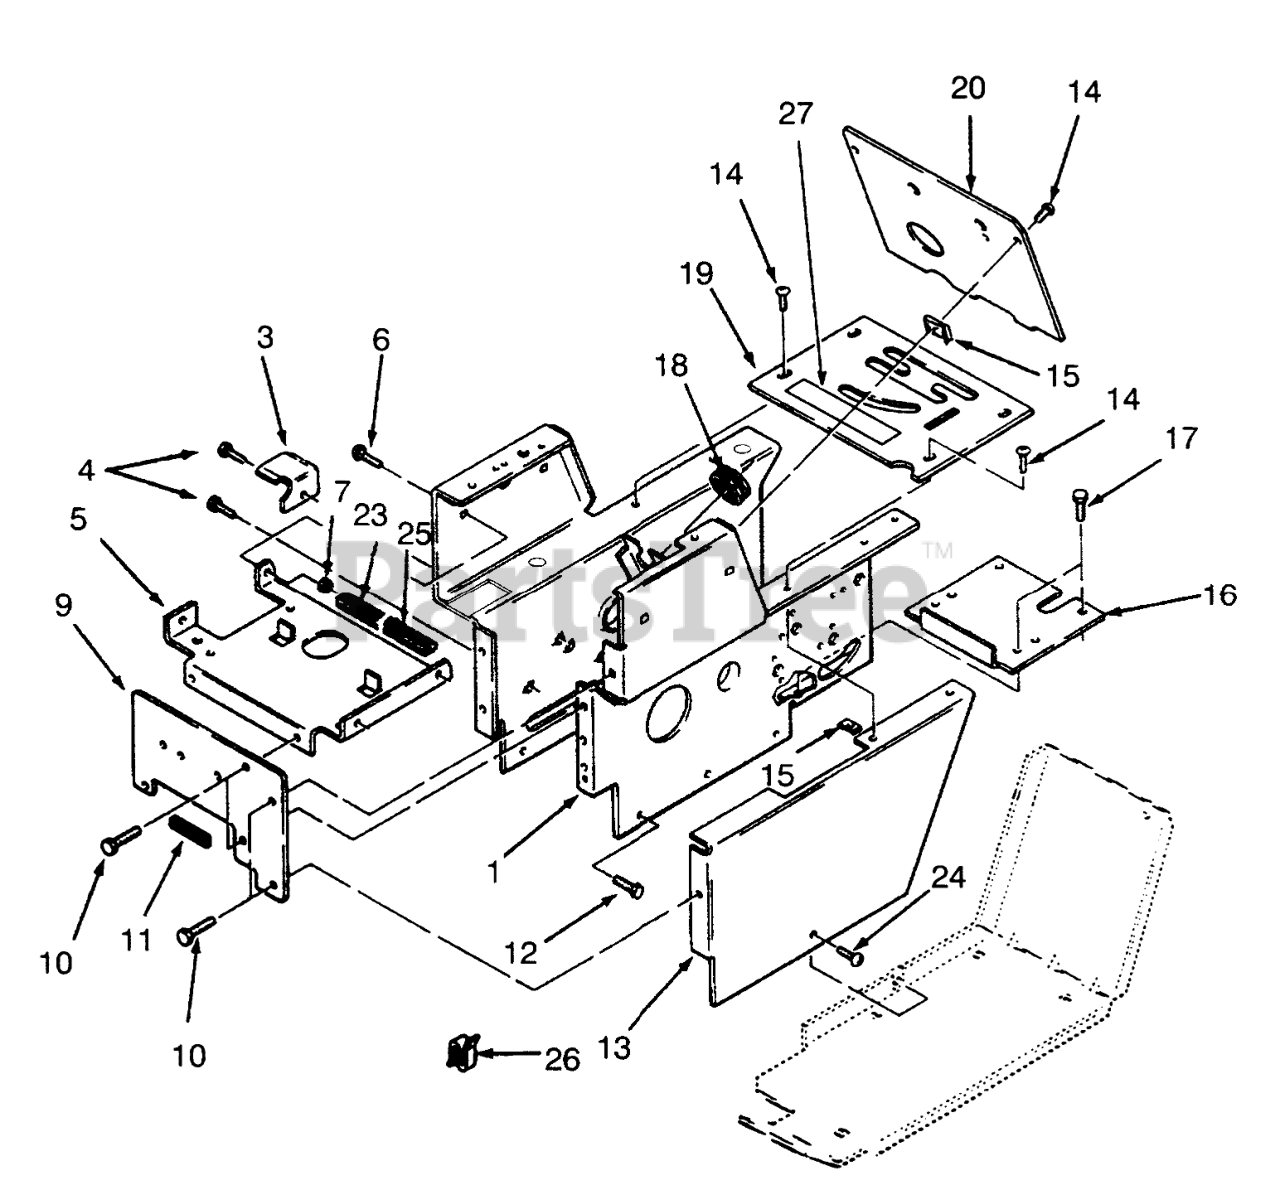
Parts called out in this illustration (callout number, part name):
1	Handstand
3	Belt Bracket
4	Bolt
5	SUPORT-BATERYB
6	BOLT CARR. 5/16X1/2 BK
7	Nut
9	Front Plate
10	Bolt
11	EDGE TRIM 4IN OF 102896
12	Bolt
13	Cover-Side LH
14	SCREW-PPH
16	Cover-Dust
17	Bolt
18	GROMMET
19	Plate-Shift Cover (Incl. Ref.#27)
20	Plate-Hood Stand
23	EDGE TRIM 5" OF 102896
24	SCREW-PPH
25	EDGE TRIM 2" 102896
26	SPEED CLIP
27	DECAL-DANGER
